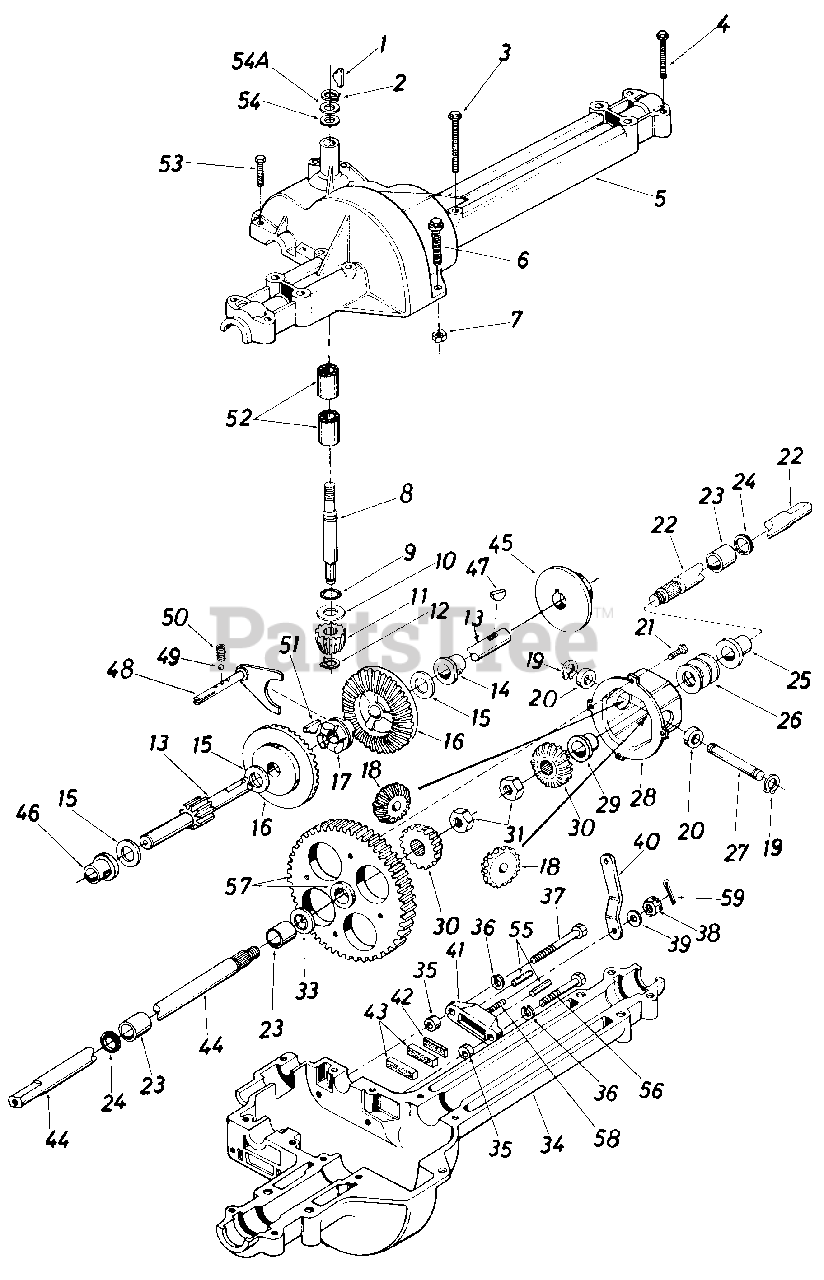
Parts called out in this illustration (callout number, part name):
1	#4 Hi-Pro Key 3/32 x 5/8" Dia.
2	Snap Ring .625" Shaft
3	Hex Bolt 1/4-20 x 1.75" Lg.
4	Hex Bolt 1/4-20 x 1.25" Lg.
5	Upper Housing
6	Hex Fl-Bolt 1/4-20 x .88" Lg.
7	Hex Nut 1/4-20 Thd.*
8	Input Shaft
9	Square Seal 5/8" I.D.
10	Thrust Washer 5/8" I.D. x 1.25" O.D.
11	Pinion Input 14T
12	Retaining Ring 7/16" Ext.
13	Drive Shaft R.H.
14	Flange Brg. 5/8" I.D. x 3/4" Lg.*
15	Fl-Wash. 5/8" I.D. x 1.0" O.D. x .020 Thk.
16	Bevel Gear 42T
17	Clutch Collar
18	Miter Gear 15T
19	Snap Ring
20	Thrust Bearing 1/2" I.D. x 1.0" O.D.
21	Pan Head Scr. 1/4-20 x .50" Lg. w/Patch
22	Axle R.H.
23	Sleeve Bearing 3/4" I.D. x 1.0" Lg.
24	Oil Seal 3/4" I.D.
25	Flange Bearing 3/4" I.D. x 15/16" Lg.
26	Fl-Wash. .760" I.D. x 1.49" O.D.
27	Cross Shaft
28	Differential Housing Ass'y.
30	Miter Gear
31	Hex Ins. L-Nut 1/2-20 Thd.
33	Fl-Wash. .760" I.D. x 1.49" O.D.
34	Lower Housing
35	Spacer .53" O.D. x 3/8 Lg.
36	L-Wash. 1/4" I.D.
37	Hex Bolt 1/4-20 x 1.50" Lg. Grade 5
38	Castle Nut 5/16-24 Thd.
39	Fl-Wash. .344" I.D. x .875" O.D.
40	Actuating Arm R.H.
41	Brake Yoke
42	Puck Plate
43	Brake Puck
44	Axle L.H.
45	Brake Disc
46	Flange Bearing 5/8" I.D. x 15/16" Lg.
47	Woodruff Key 3/16 x 5/8 HT
48	Shift Fork Ass'y.
49	Ball Detent.250n Dia.
50	Spring Detent
51	#9 Hi-Pro Key 3/16" x 3/4" Dia. HT
52	Needle Brg. 5/8n l.D. x 1/2" Lg.
53	Hex Bolt 1/4-20 x 1 oOn Lg.
54	Fl-Wash. 5/8n l.D. x .030
54A	Fl-Wash. 5/8" I.D. x .040
55	Actuating Pin 5/16" Dia.
56	Hex Bolt 1/4-20 x 1.50" Lg. Grade 5
57	Differential Gear 72T Ass'y. w/Bearing
58	Sq. Hd. Bolt 5/16-24 Thd.
59	Hex Jam Nut 5/16-24 Thd.
